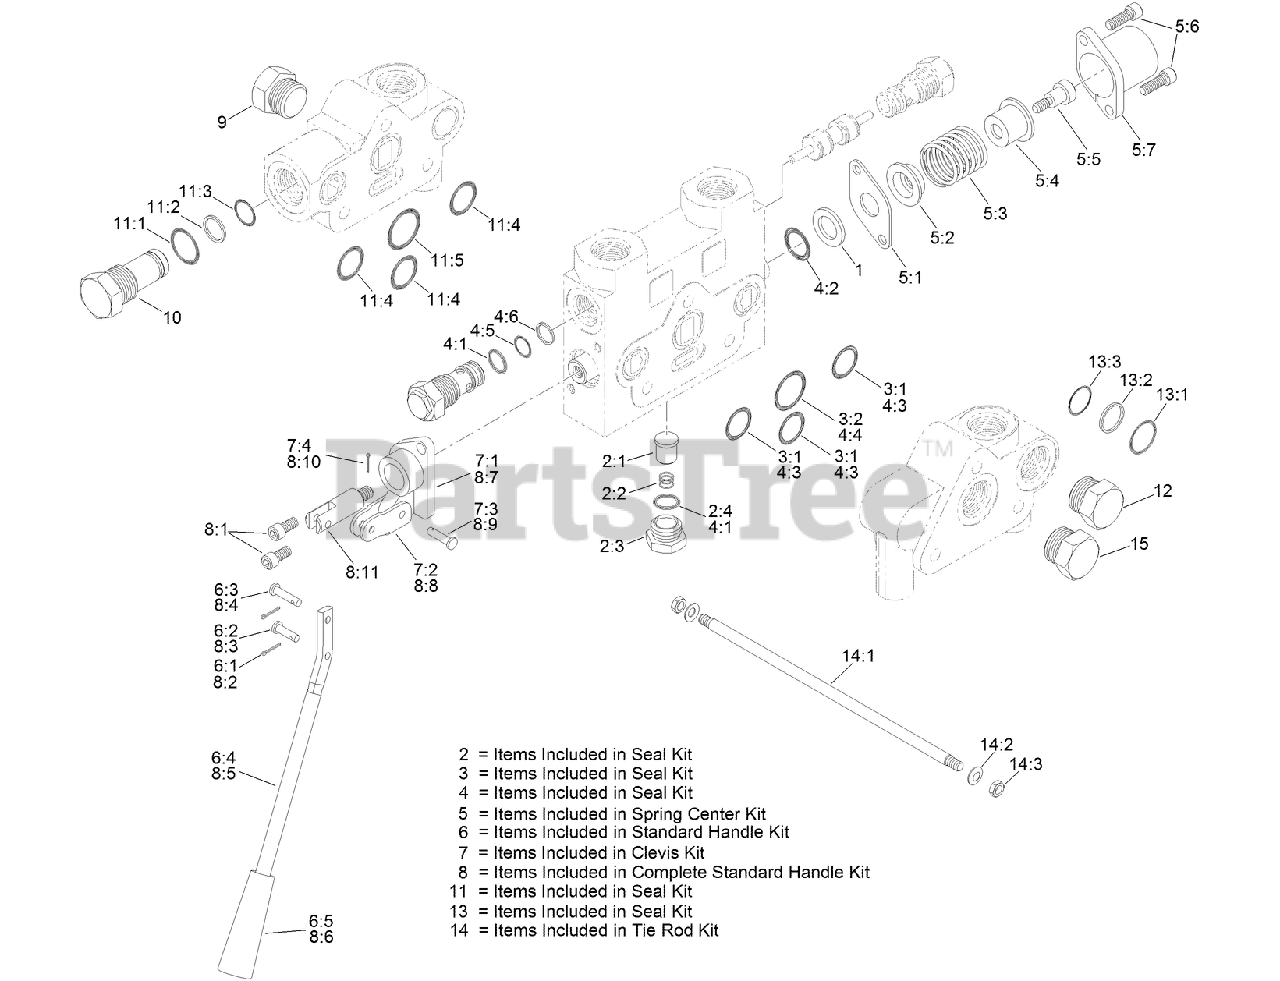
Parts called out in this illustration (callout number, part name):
1	WASHER-BACK UP, SPOOL
2	LOAD CHECK KIT
2:1	POPPET-CHECK, LOAD
2:2	SPRING-CHECK, LOAD
2:3	PLUG-CHECK, LOAD
2:4	O-RING
3	REPLACEMENT SEAL KIT
3:1	O-RING
3:2	O-RING
4	SEAL KIT
4:1	O-RING
4:2	O-RING
4:3	O-RING
4:4	O-RING
4:5	O-RING
4:6	Backup Washer
5	SPRING CENTER KIT
5:1	PLATE-RETAINER
5:2	CUP-STOP, INNER
5:3	Spring-Centering
5:4	CUP-STOP, OUTER
5:5	ADAPTER-SPOOL
5:6	Screw-Cap
5:7	Cap-End
6	STANDARD HANDLE KIT
6:1	Pin-Cotter
6:2	Pin-Clevis
6:3	Pin-Clevis
6:4	Handle
7	CLEVIS KIT
7:1	Clevis
7:2	Link
7:3	Pin-Clevis
7:4	Pin-Cotter
8	STANDARD HANDLE KIT
8:1	Screw-Cap
8:2	Pin-Cotter
8:3	Pin-Clevis
8:4	Pin-Clevis
8:5	Handle
8:7	Clevis
8:8	Link
8:9	Pin-Clevis
8:10	Pin-Cotter
8:11	ADAPTER-SPOOL
9	PLUG-PORT
10	PLUG-NO RELIEF
11	REPLACEMENT INLET SEAL KIT
11:1	O-RING
11:2	Washer-Back Up
11:3	O-RING
11:4	O-RING
11:5	O-RING
13	OUTLET SECTION SEAL KIT
13:1	O-RING
13:2	Washer-Back Up
13:3	O-RING
14	TIE ROD KIT (3 SECTION)
14:1	Rod-Tie
14:2	Washer-Lock
14:3	NUT
15	PLUG-CONVERSION, CENTER OPEN
